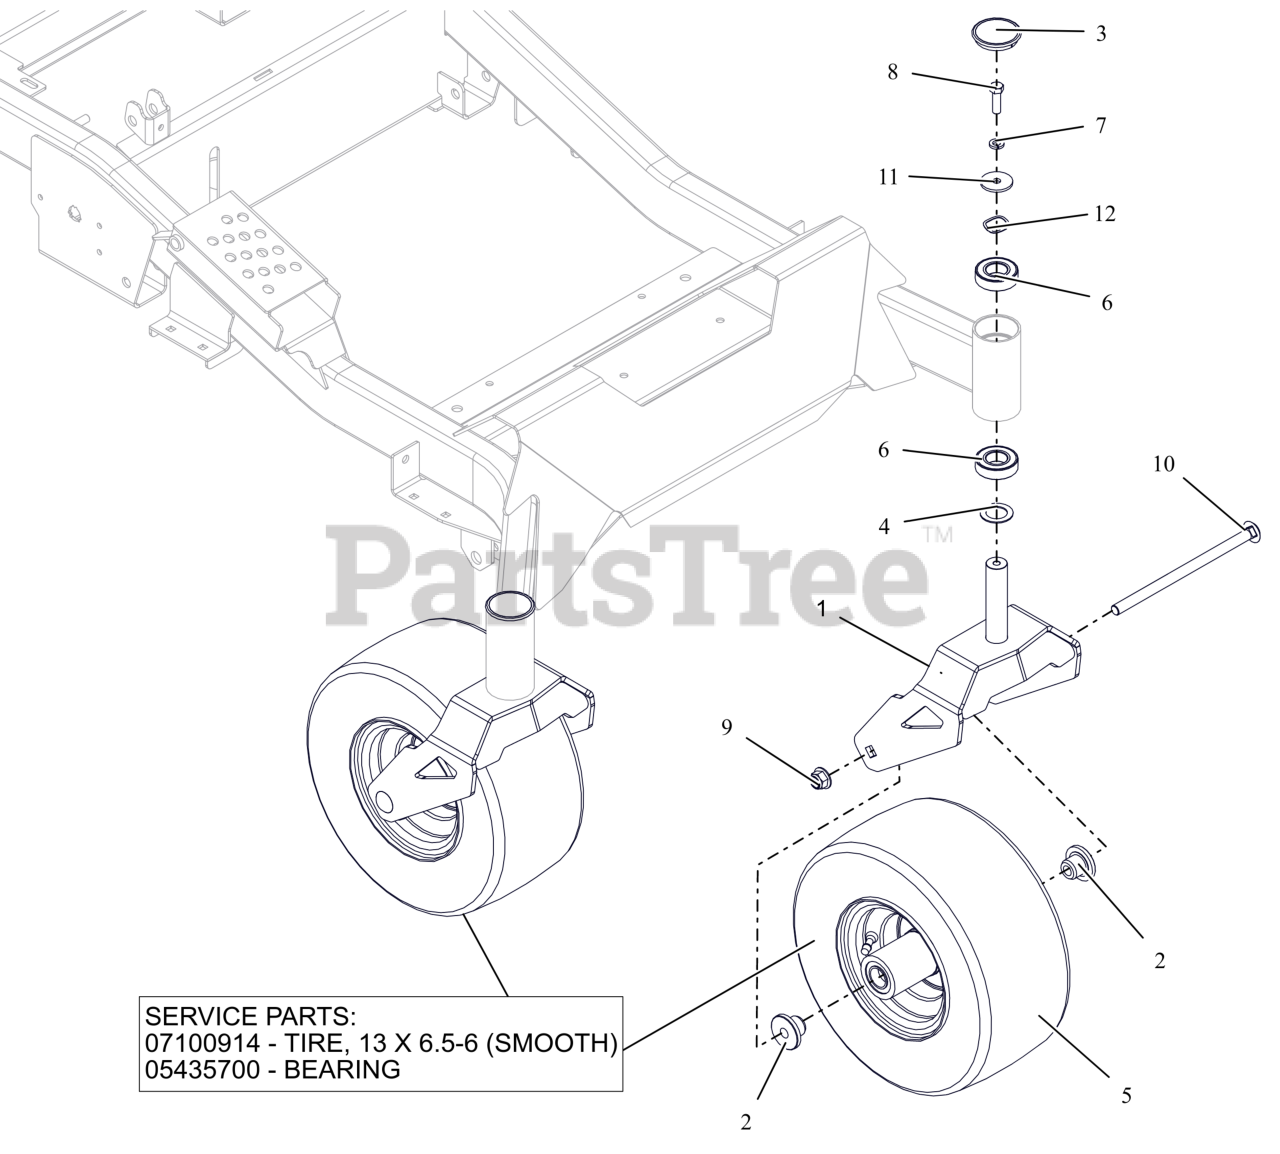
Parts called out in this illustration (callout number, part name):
1	WLDMT, CASTER FORK-APEX (ORANGE)
2	SPACER, FRONT WHEEL
3	CAP, DUST
4	WSHR-HRD-THRS 1.007X1.542X.062
5	ASM, WHL/TIRE 13X6.50-6
5	TIRE, 13X6.50-6 SMOOTH
5	BRG, 25MM ID X 52MM OD X 15MM
6	BRG,BALL 1.00X2.00X.563(1641)
7	WSHR, LK-HVY .375X.115 ZCC
8	BLT, HEX .38-16X1.25 G5 ZCC
9	NUT,NYL-FLG .50-13 GF ZCC
10	BLT, RHSN .50-13X9.00 G5 ZCC
11	WSHR, FLT .380X1.50X.125 ZCC
12	WSHR-WAVE 1.0X1.25X.028 .145FH
